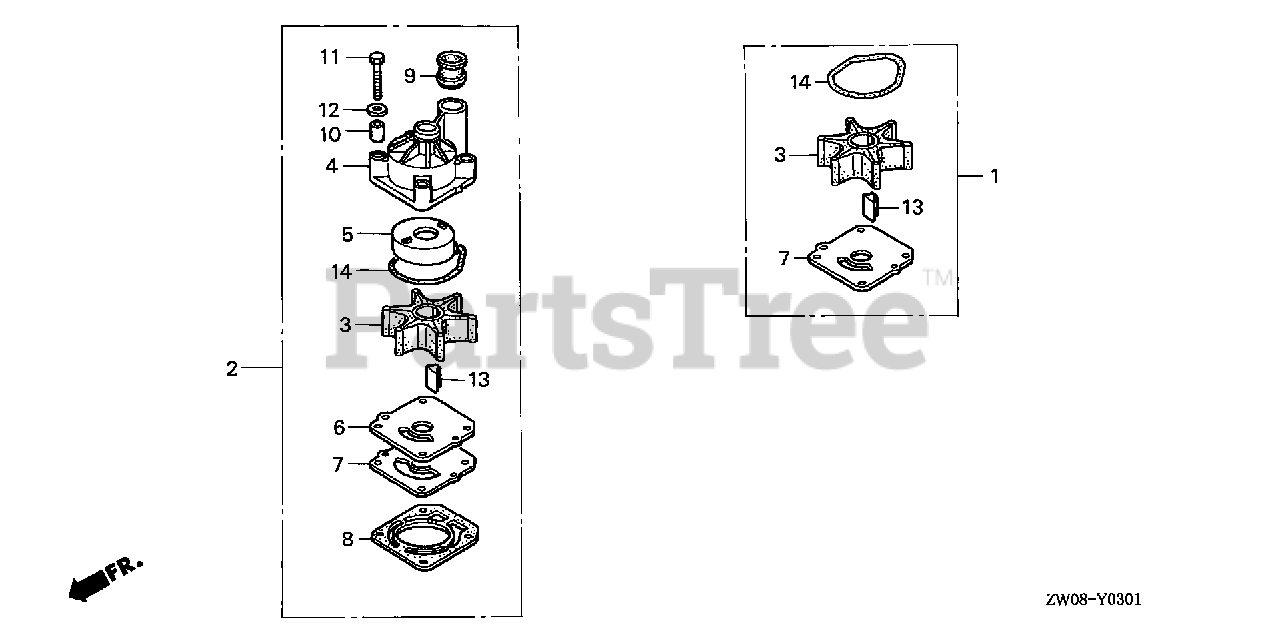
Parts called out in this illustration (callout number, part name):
1	PUMP KIT, IMPELLER
2	PUMP KIT, IMPELLER
3	IMPELLER, PUMP
4	HOUSING, IMPELLER
5	LINER, PUMP
6	COVER, IMPELLER
7	GASKET B, IMPELLER
8	GASKET, WATER PUMP
9	RING, WATER TUBE SEAL
10	COLLAR, DISTANCE
11	BOLT, HEX. (8X55)
12	WASHER, PLAIN (8MM)
13	KEY, WOODRUFF
14	O-RING, WATER PUMP
